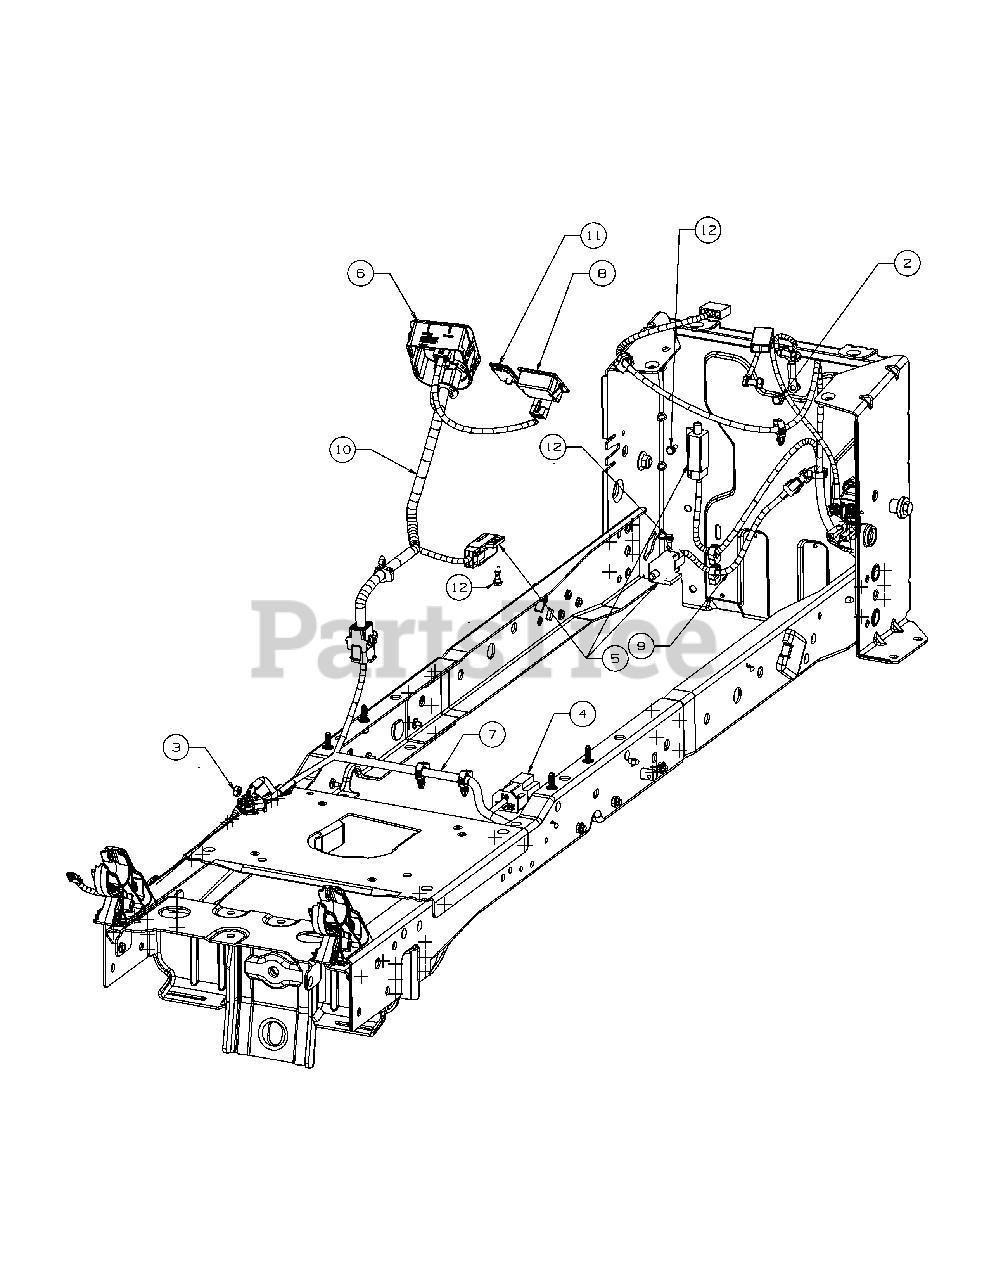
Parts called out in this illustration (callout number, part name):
1	Screw-Hxacrnwsh M6-
2	Screw Hex.Wash.Hd
3	Nut-Hex Jamlk 1/4-20
4	Switch-3 Pole Nc
5	Switch, Interlock
6	Key Switch (Man. PTO) RMC
6	Ignition Key
7	Harness Assembly, Main (Manual PTO)
8	Hour Meter/Service Minder
9	Harness-Reverse
10	Dash Harness (Man. PTO) RMC
11	Plug:Dash:Man PTO
12	Screw:Shldr:T:#10-32:.500
